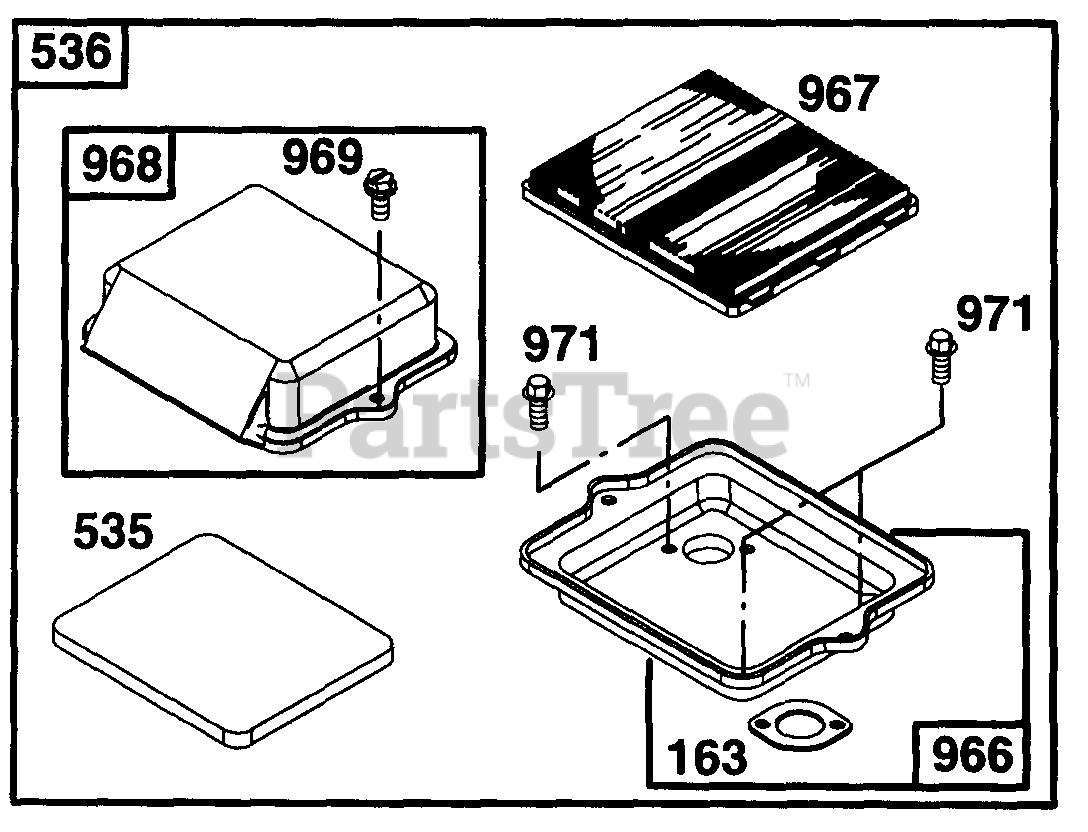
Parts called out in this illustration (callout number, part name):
163	Gasket-Air Cleaner Mounting
535	Element-Air Cleaner
536	Cleaner-Air
966	Base-Air Cleaner
967	Filter-Air Cleaner
968	Cover-Air Cleaner
969	Screw-Air Cleaner
971	Screw-Hex
